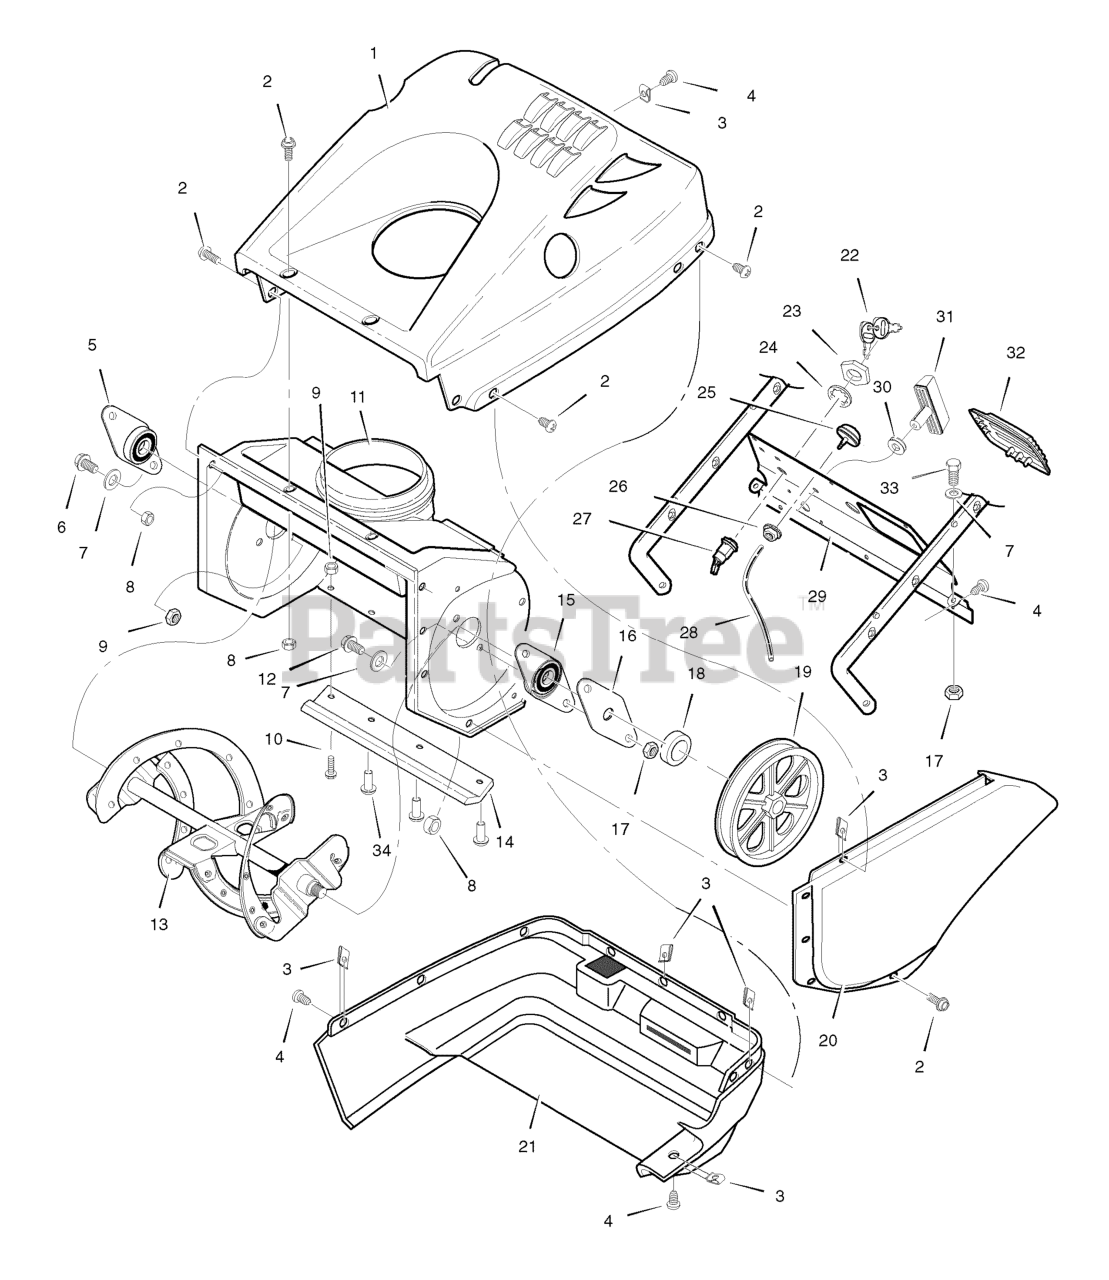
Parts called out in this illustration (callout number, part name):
1	COVER, TOP
2	SCREW, #10-24 X 0.50
3	NUT, 1/4-10 SPEED J-TYPE
4	SCREW, 1/4-14 X 0.75
5	BEARING, FLANGE
6	SCREW, 1/4-20 X 1.00
7	WASHER, FLAT, .281 X .63 X .065
8	NUT, #10-24 HEX CONTROL LOCK
9	NUT, 1/4-20 HEX CONTROL LOCK
10	SCREW, 1/4-20 X 0.75
11	AUGER HOUSING ASSEMBLY
12	SCREW, 1/4-20 X 0.63
13	AUGER ASSEMBLY, COMPLETE
14	BLADE, SCRAPER
15	PLATE & BEARING ASSY
16	PLATE, RETAINER BEARING
17	NUT, 1/4-20 HEX CONTROL LOCK
18	SPACER, SLEEVE
20	COVER, BELT
21	COVER, BOTTOM
22	SET, Key
23	NUT, 5/8-32
24	WASHER, .640 X 1.1 X .05
25	PRIMER, CARBURETOR
26	NUT, 1/-20 HEX KEPS
27	SWITCH, IGNITION 45 DEGREE
28	HOSE, PRIMER 9.5"
29	PANEL, CONTROL
30	GROMMET & WASHER, ROPE
31	GRIP, Starter Rope
32	PANEL, ACCESS
33	SCREW, 1/4-20 X 1.25
34	RIVET, OFFSET, .25 X .61
